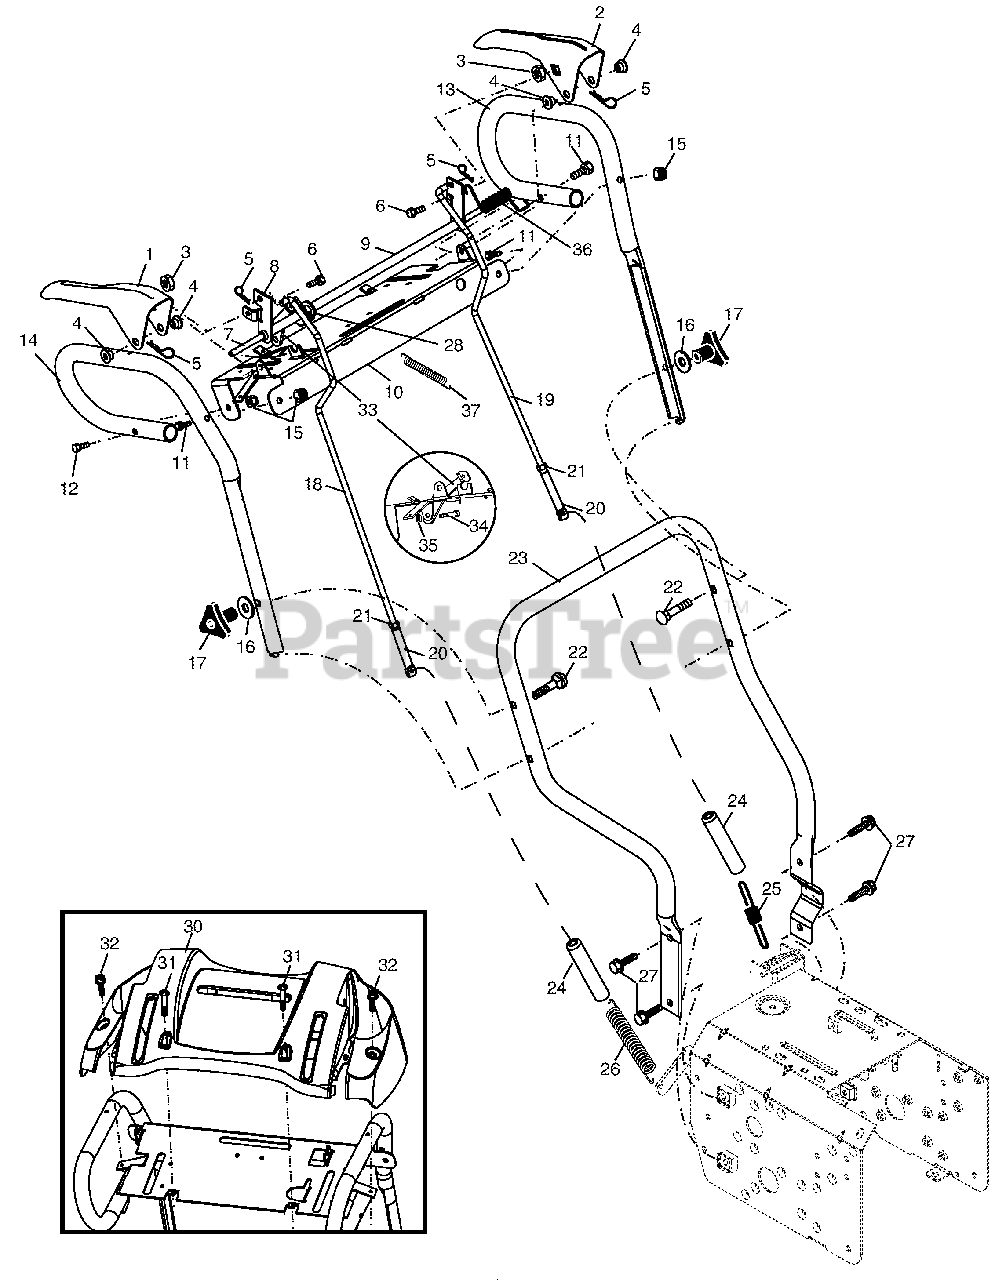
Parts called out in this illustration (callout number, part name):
1	Lever, Auger Control, RH
2	Lever, Traction Drive Control, LH
3	Nut, Cage 1/4-20
4	Bushing, Flange
5	Retainer, Hairpin
6	Screw, Hex Head 1/4-20 x 3/4
7	Rod, Interlock
8	Tube Assembly, Interlock, RH
9	Tube Assembly, Interlock, LH
10	Panel, Control
11	Screw, Hex Head 5/16-18 x 1-1/2
12	Screw, Hex Head 5/16-18 x 1-3/4
13	Handle Tube, LH
14	Handle Tube, RH
15	Nut, Lock 5/16-18
16	Washer, Flat 3/8
17	Knob, Handle
18	Rod, Auger Control
19	Rod, Traction Control
20	End, Control Rod
21	Nut, Hex, Jam 5/16-18
22	Bolt, Carriage 3/8-16 x 2-1/4
23	Handle Tube, Lower
24	Sleeve, Spring
25	Spring, Traction Drive
26	Spring, Auger Control
27	Screw, Hex Head 3/8-16 x 1
28	Clip, Panel
30	Console, Panel
31	Screw, Hex Head, Tapping #10-24 x 1-1/4
32	Screw, Hex Head, Tapping #10-24 x 1/2
33	Latch, Interlock
34	Bolt, Shoulder
35	Nut, Lock 1/4-20
36	Spring, Torsion
37	Spring, Interlock
